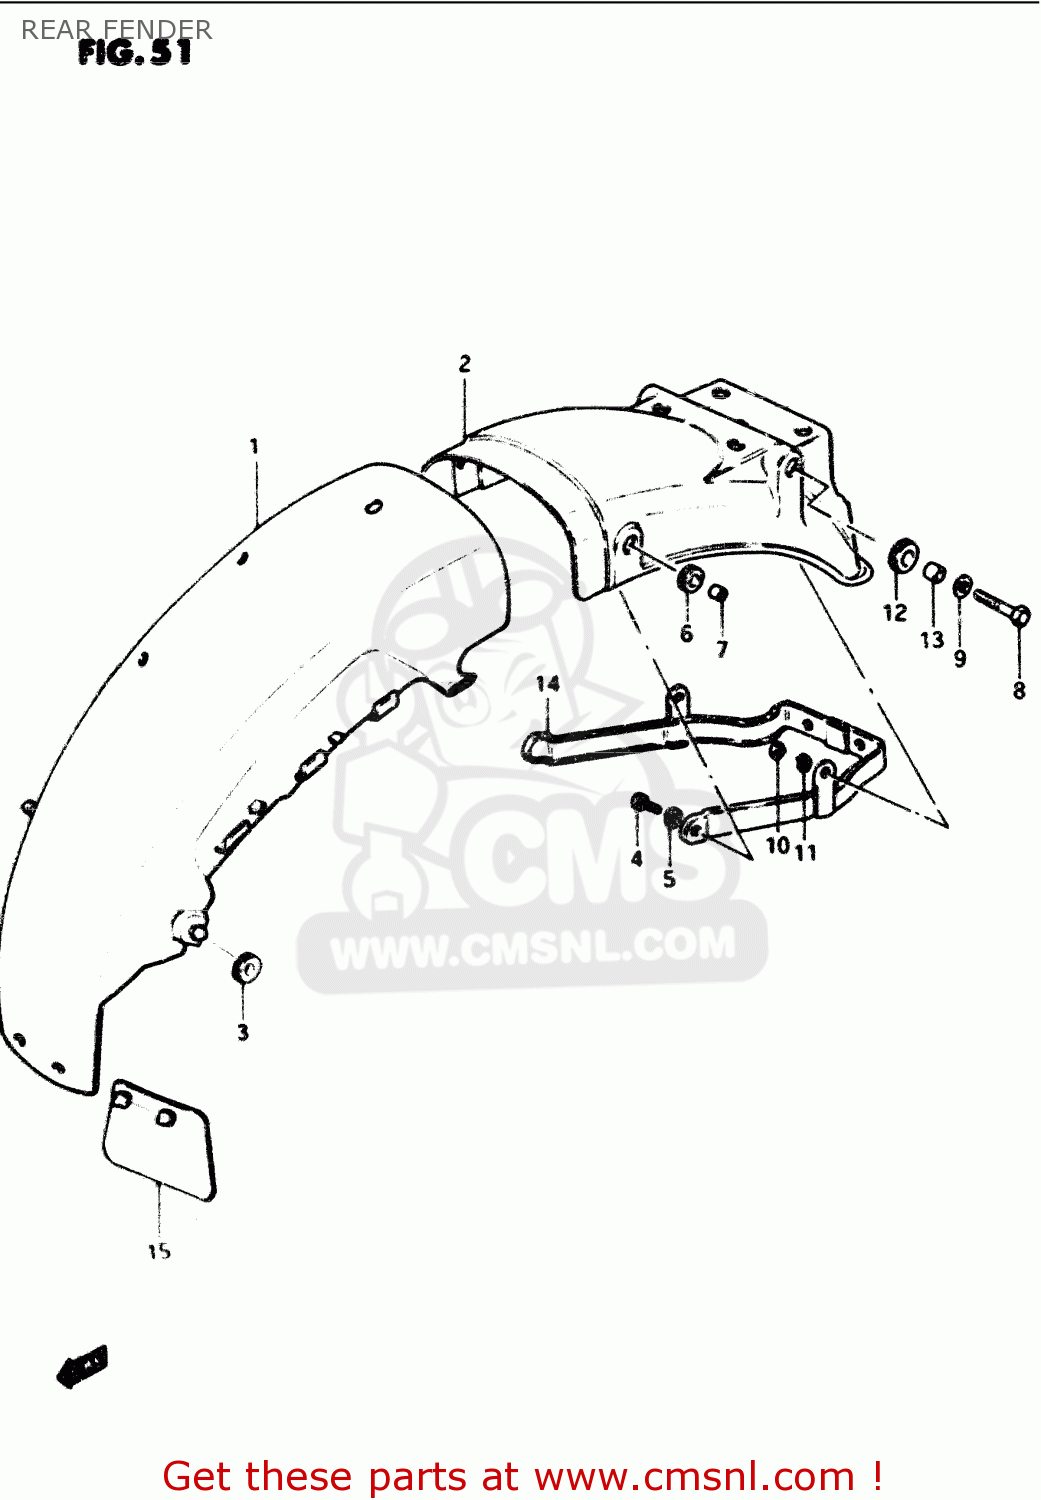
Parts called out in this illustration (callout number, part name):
1	BODY,RR FENDER FR
2	FENDER,REAR
3	CUSHION
4	BOLT, UPPER
5	WASHER,LOCK
6	CUSHION
7	SPACER(6.1X9X7.5)
8	BOLT 8X40
9	WASHER
10	NUT
11	LOCK WASHER
12	CUSHION
13	SPACER (8.2X12X7.5)
14	REINFORCEMENT,REAR FENDER
15	GUIDE,RR FENDER MUD
